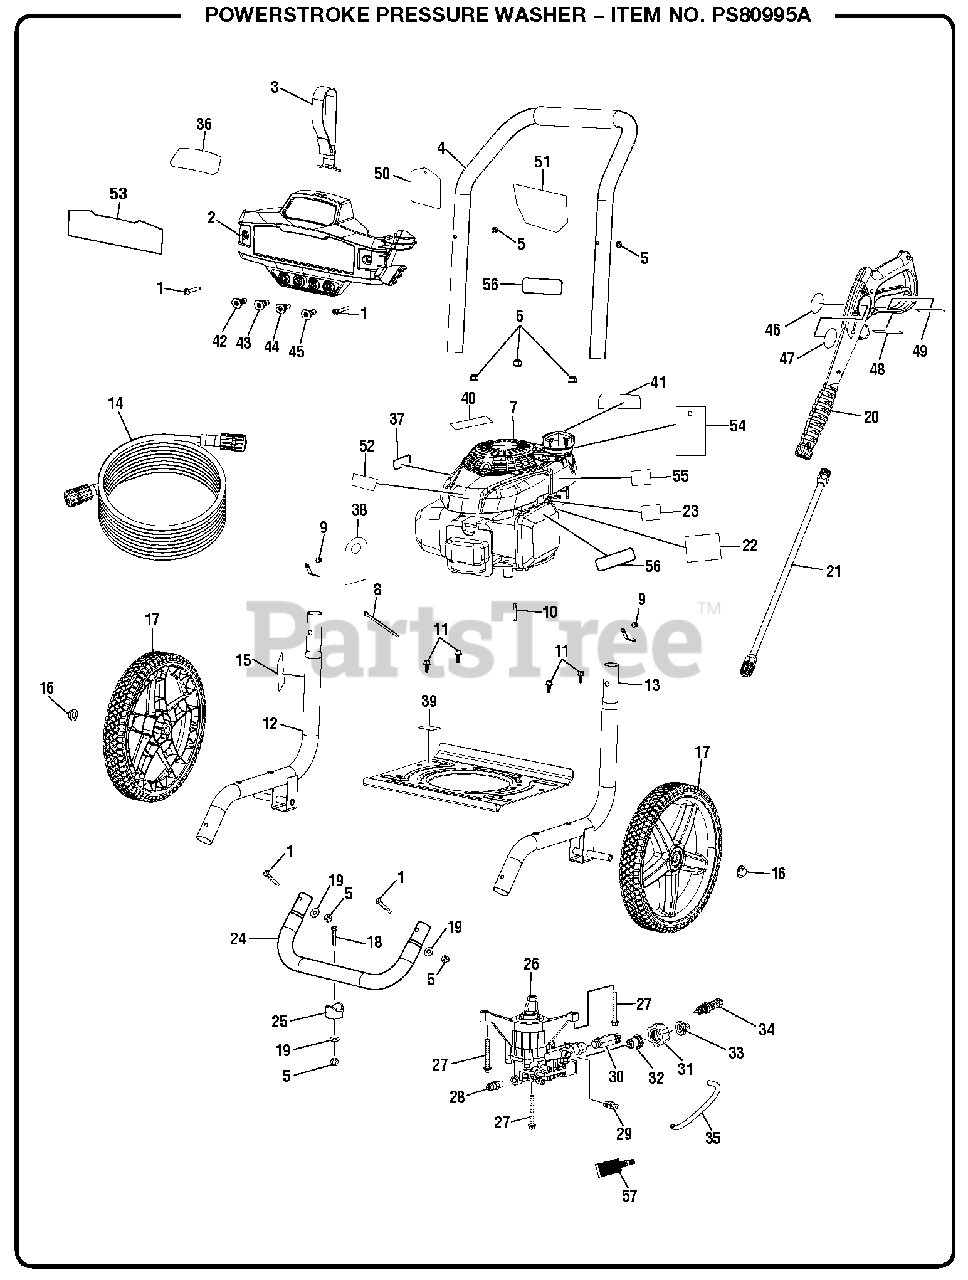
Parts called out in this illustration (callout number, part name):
1	Bolt (M6 x 42 mm, T30 Torx Pan Hd.)
2	Hose And Nozzle Assembly
3	Hose Strap
4	Handle Assembly w/ Foam
5	Lock Nut (M6 x 1)
6	Flange Lock Nut (M8 x 1.25)
9	Handle Spring Clip
10	Output Shaft Key
11	Bolt (M6 x 1 x 16 mm, Hex Hd.)
12	Main Frame Assembly (Left)
13	Main Frame Assembly (Right)
15	Data Warning Label
16	Push Cap Nut
18	Screw (M6 x 1 x 48 mm, T30 Torx Pan Hd.)
19	Washer (1/4 in.)
20	Trigger Handle Assembly
21	Wand Assembly
22	Fuel Valve & Choke Label
23	On/Off Label
24	Front Frame Assembly
26	Pump
27	Flange Bolt (M8 x 1.25 x 60 mm, Hex Hd.)
28	Thermal Release Valve
29	Soap Injector Kit
30	Outlet Tube
33	Filter Screen (Pump Inlet)
34	Unloader Valve Assembly
35	Chemical Siphon Tube
36	Logo Label
37	Hot Surface Label
38	Oil Dipstick Hangtag
39	Oil Fill Location Label
40	Combustion Warning Label
41	Danger Label
42	25deg Nozzle
43	40deg Nozzle
44	0deg Nozzle
45	Soap Nozzle
46	Label (Trigger Handle Logo)
47	Label (Trigger Handle Warning)
48	Label (Trigger Handle Rating)
49	Label (Trigger Handle Warning, French & Spanish)
50	Standard Nozzle Hangtag
51	Quick Start Label
52	Honda Label
53	Performance Label
54	Warning Hangtag
55	E85 Label
56	Inquiries Label
57	Chemical Siphon Filter
